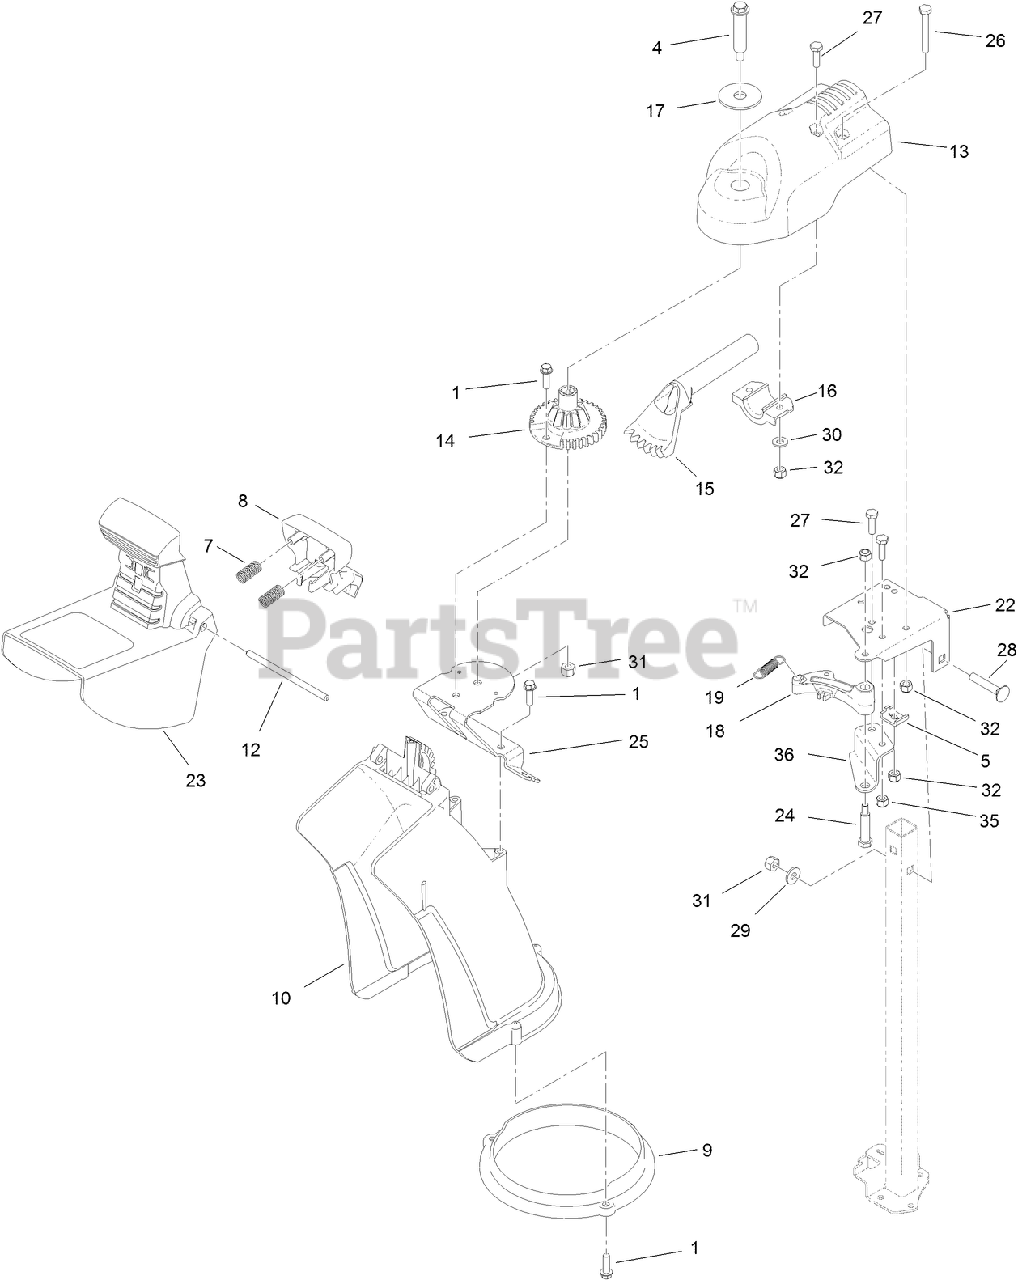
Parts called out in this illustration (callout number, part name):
1	SCREW-HWH
4	BOLT-SHOULDER
5	CLAMP-CABLE
8	TRIGGER-DEFLECTOR
9	RING-CHUTE
13	MOUNT-CHUTE, DISCHARGE
14	GEAR-CHUTE
15	GEAR-BEVEL
16	MOUNT-GEAR, BEVEL
17	WASHER-FLAT
18	LATCH-CHUTE
19	SPRING-LATCH, CHUTE
22	BRACKET-SUPPORT, CHUTE
23	DEFLECTOR-CHUTE
24	BOLT-SHOULDER
25	BRACKET-MOUNT, CHUTE
26	SCREW-HH
27	SCREW-HH
28	BOLT-CAR
29	WASHER-FLAT
30	WASHER-FLAT
31	NUT-LOCK, NI
32	NUT-LOCK, NI
35	NUT-LOCK, NI
36	BRACKET-SUPPORT, LATCH
